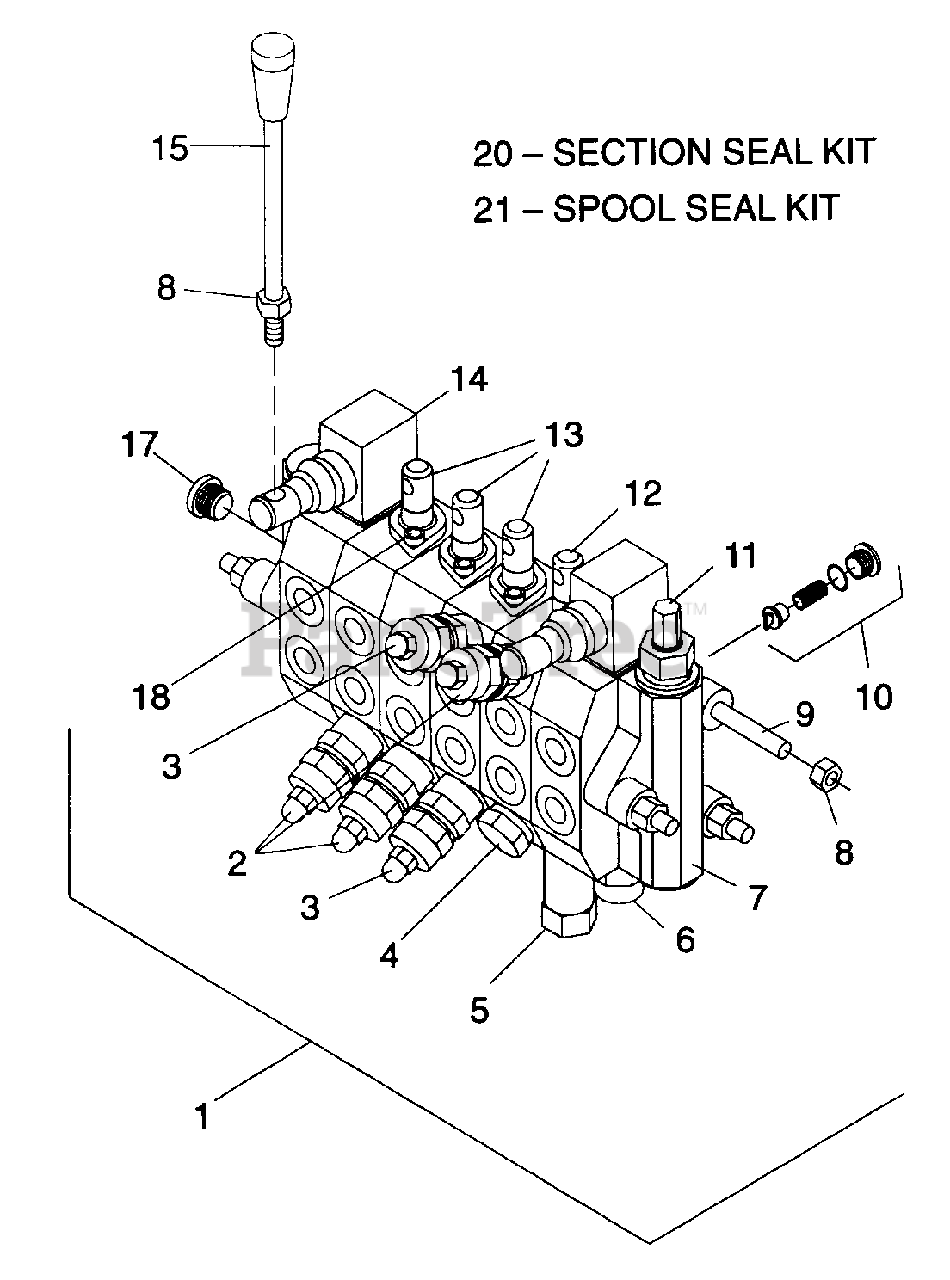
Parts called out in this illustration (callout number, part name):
1	Console Valve
2	Shock/dampening valve 2500 psi
3	Port relief valve/anti-cav 2100 psi
4	Plug, Port relief cavity
5	Spool position control assembly
6	SPool position control assembly
7	Valve inlet section
8	8mm x 1.25P Hex nut
9	8mm x 1.25P x 276mm Hex head cap screw
10	Check valve assembly
11	Relief valve assembly
12	Boom section with relief
13	Valve spool section without relief
14	Control assembly - Stabilizer
15	Control handle - Stabilizer
17	Plug, 3/4 SAE M with O-ring
18	5mm x .8P x 12mm Hex head cap screw
